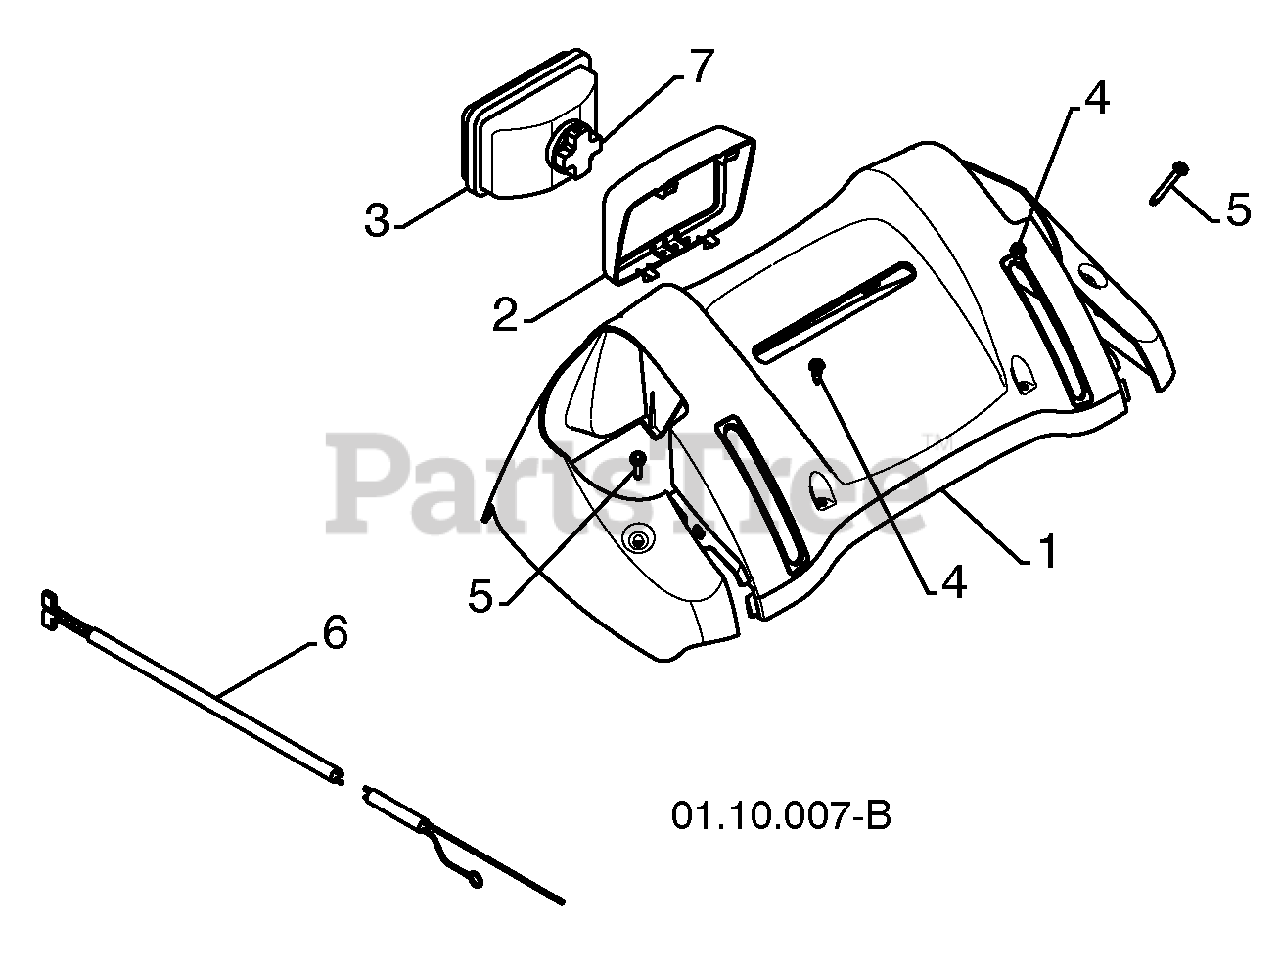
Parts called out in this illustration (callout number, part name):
1	CONSOLE PANEL
2	HEADLIGHT BEZEL
3	FLOOD HEADLIGHT
4	SHOULDER SCREW 10-24 X .625
5	SCREW 10-24 X 1.25
6	WIRE HARNESS
7	BULB
